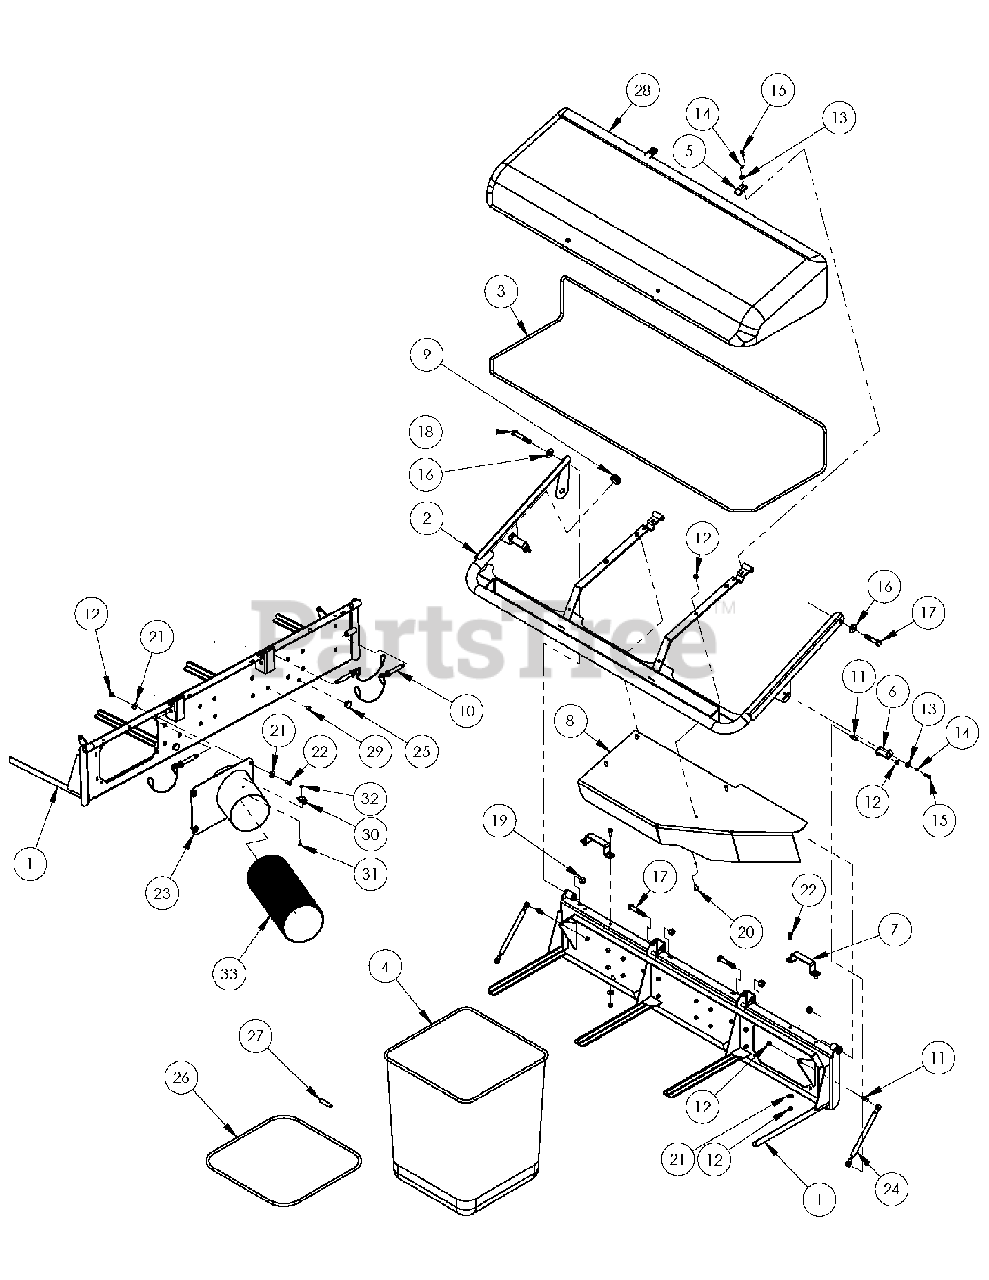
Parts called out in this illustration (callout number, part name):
1	3 BAG CATCHER BAG SUPPORT MOUNT
2	3-BAG CAP SUPPORT
3	AIR DOME FRAME, 3 BAG-3/8" ROD ONE
4	COMMERICAL CATCHER BAG
5	BRACKET-SINGLE HOLE MOUNT
6	BRACKET-GAS CYLINDER MOUNT
8	3 -BAG DEFLECTOR
9	PLUG, BLACK PLASTIC-1 1/2" TUBE
10	DETENT PIN W/ LANYARD-1/2" X 2 1/2" LONG
11	BALL JOINT
12	HEX NUT, NYLON INSERT-5/16"-18
13	FLAT WASHER-1/4"
14	LOCK WASHER-1/4"
15	CAP SCREW-1/4-20 X3/4" LONG
16	FLAT WASHER-1/2"
17	CAP SCREW-1/2"-13 X 2 1/2" LONG
18	CAP SCREW-1/2"-13 X 3" LONG
19	HEX NUT, NYLON INSERT-1/2"-13
20	PAN HEAD SCREW-5/16"-18 X 3/4" LONG
21	FLAT WASHER-5/16" LONG
22	CAP SCREW-5/16"-18 X 3/4" LONG
23	6" INLET TUBE ASSEMBLY
24	GAS CYLINDER
25	RUBBER BUMPER
26	COMMERCIAL GRASS BAG FRAME
27	PLASTIC FRAME CONNECTOR
28	AIR DOME CAP WITH "J" STRIP-PLAIN
29	PLUG, BLACK PLASTIC-7/16" HOLE
30	SPRING CLIP
31	MACHINE SCREW-#10-24 X 1/2" LONG
32	HEX NUT, NYLON INSERT-#10-24
33	3 BAG HOSE
